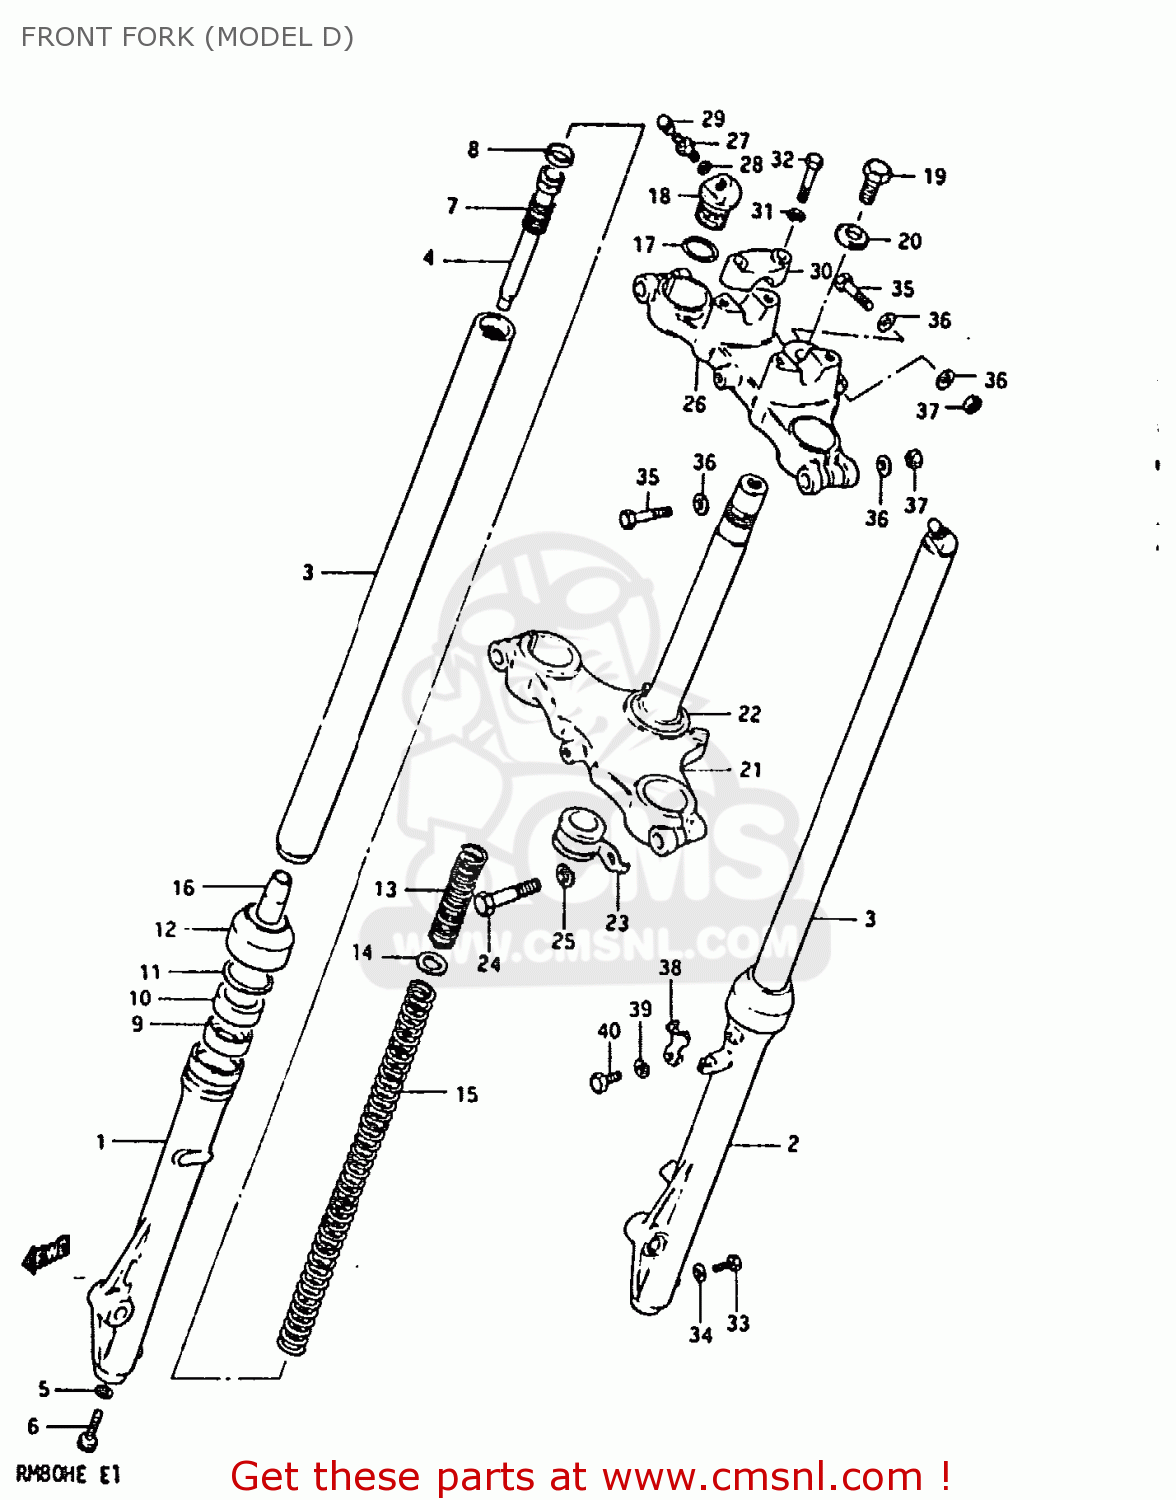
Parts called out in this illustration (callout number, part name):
1	TUBE, OUTER RH (YELLOW)
2	TUBE, OUTER LH (YELLOW)
3	TUBE, INNER
4	PIPE, SEAT
5	GASKET (NAS)
6	BOLT(8X27)
7	SPRING,FORK REBOUND
8	RING,PISTON
9	SPACER,SEAL
10	OIL SEAL,FRONT FORK
11	CIRCLIP,FORK OIL SEAL
12	BOOT
13	SPRING A
14	SPRING,JOINT
15	SPRING B
16	PIECE, OIL LOCK
17	O RING
18	BOLT
19	BOLT
20	WASHER
21	STEM, STEERING (BLACK)
22	RACE,STEERING OUTER LWR
23	CLIP
24	BOLT
25	WASHER,LOCK 12
26	STEM HEAD, STEERING (BLACK)
27	VALVE,AIR
28	O-RING
29	CAP,VALVE AIR
30	HOLDER,HANDLE UPR
31	LOCK WASHER
32	BOLT
33	BOLT
34	GASKET,DRAIN,PLUG (NAS)
35	BOLT (8*55)
36	WASHER
37	NUT
38	HOLDER
39	LOCK WASHER
40	BOLT
